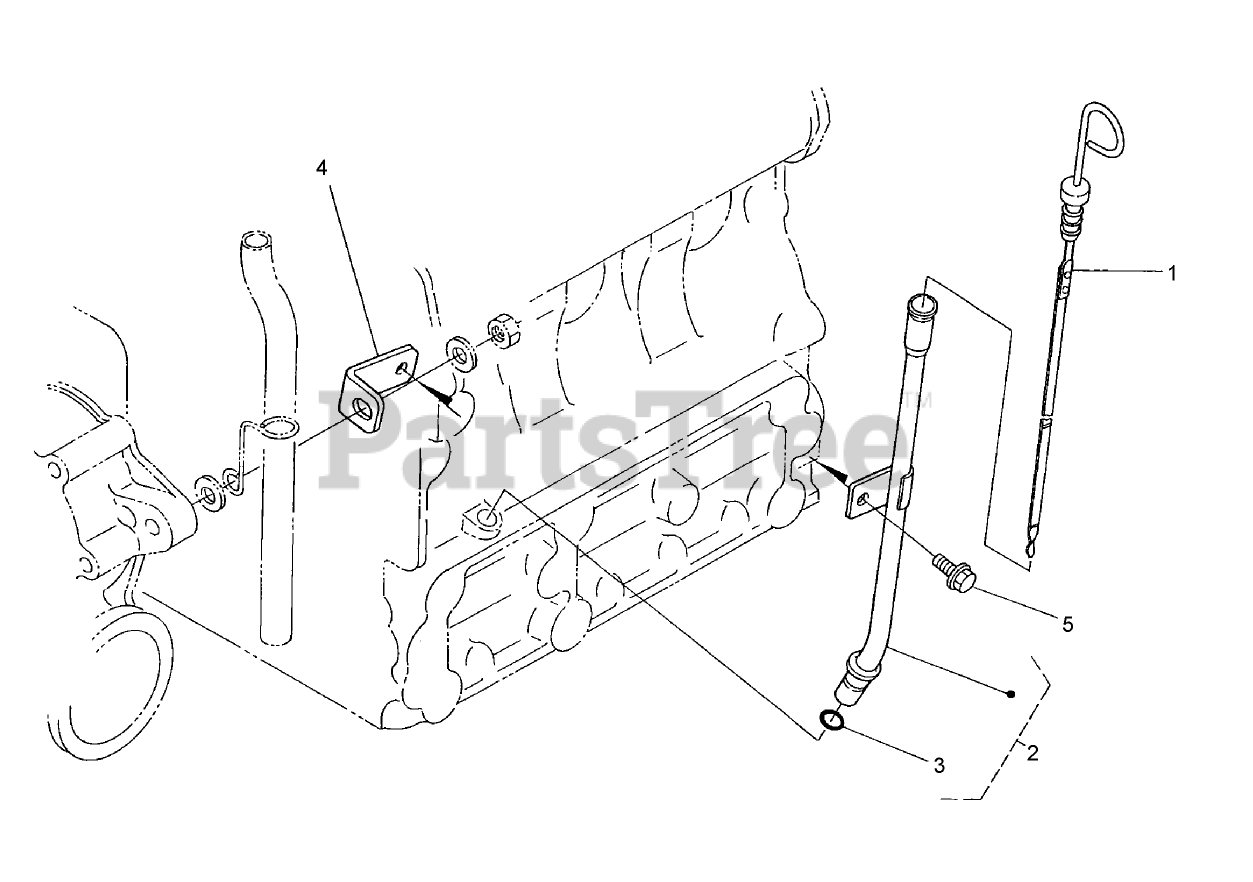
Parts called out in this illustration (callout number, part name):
1	GAUGE-OIL
2	OIL GAUGE GUIDE ASM
3	OBS O-RING
4	SUPPORT-GUIDE, GAUGE
5	BOLT-FLANGE
